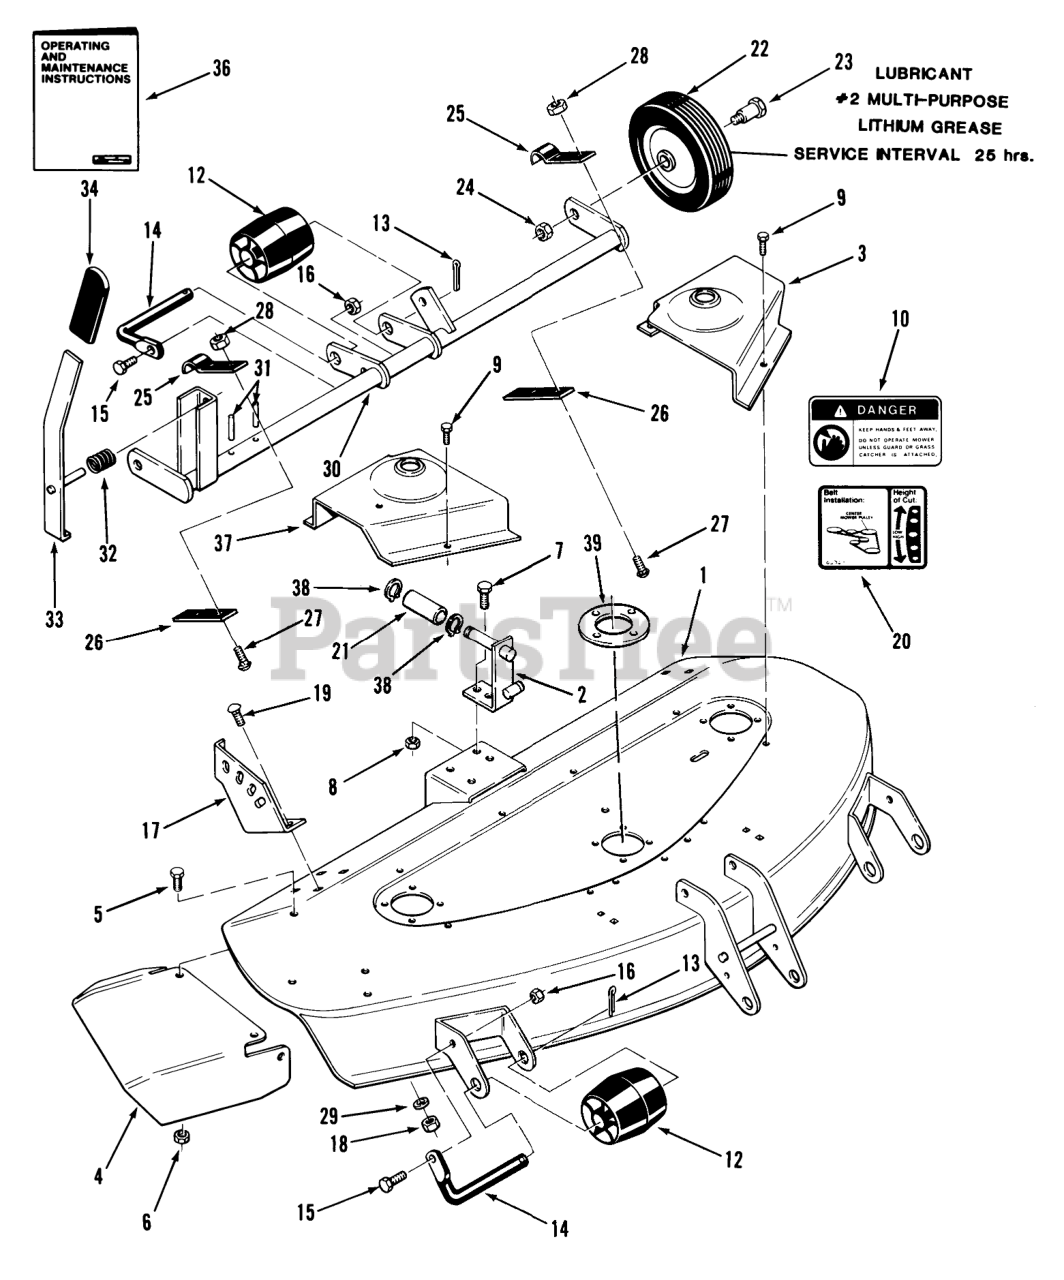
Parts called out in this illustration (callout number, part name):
1	ASSY 42" SIDE MOW R
2	ASSY BRACKET GUID R
3	COVER-BELT LH R
4	Chute Extension
5	Bolt
6	Nut
7	BOLT
8	Nut
9	SCREW -4
10	Danger Decal
12	Roller
13	Cotter Pin
14	ROLLER-SHAFT
15	H H C S
16	Nut
17	Quadrant
18	Nut
19	Bolt-Carriage
20	DECAL-HEIGHT BELT
21	SPACER
22	WHEEL
23	BOLT-SHOULDER
24	Nut
25	Clamp
26	Bar
27	Bolt
28	NUT
29	Washer
30	Gage Wheel Support
31	PIN-SPIROL
32	SPRING-COMPRESSION
33	LEVER ASSY R
36	Operating & Maintenance Instructions
37	COVER-BELT RH R
38	Snap Ring
39	PLATE-SPINDLE
